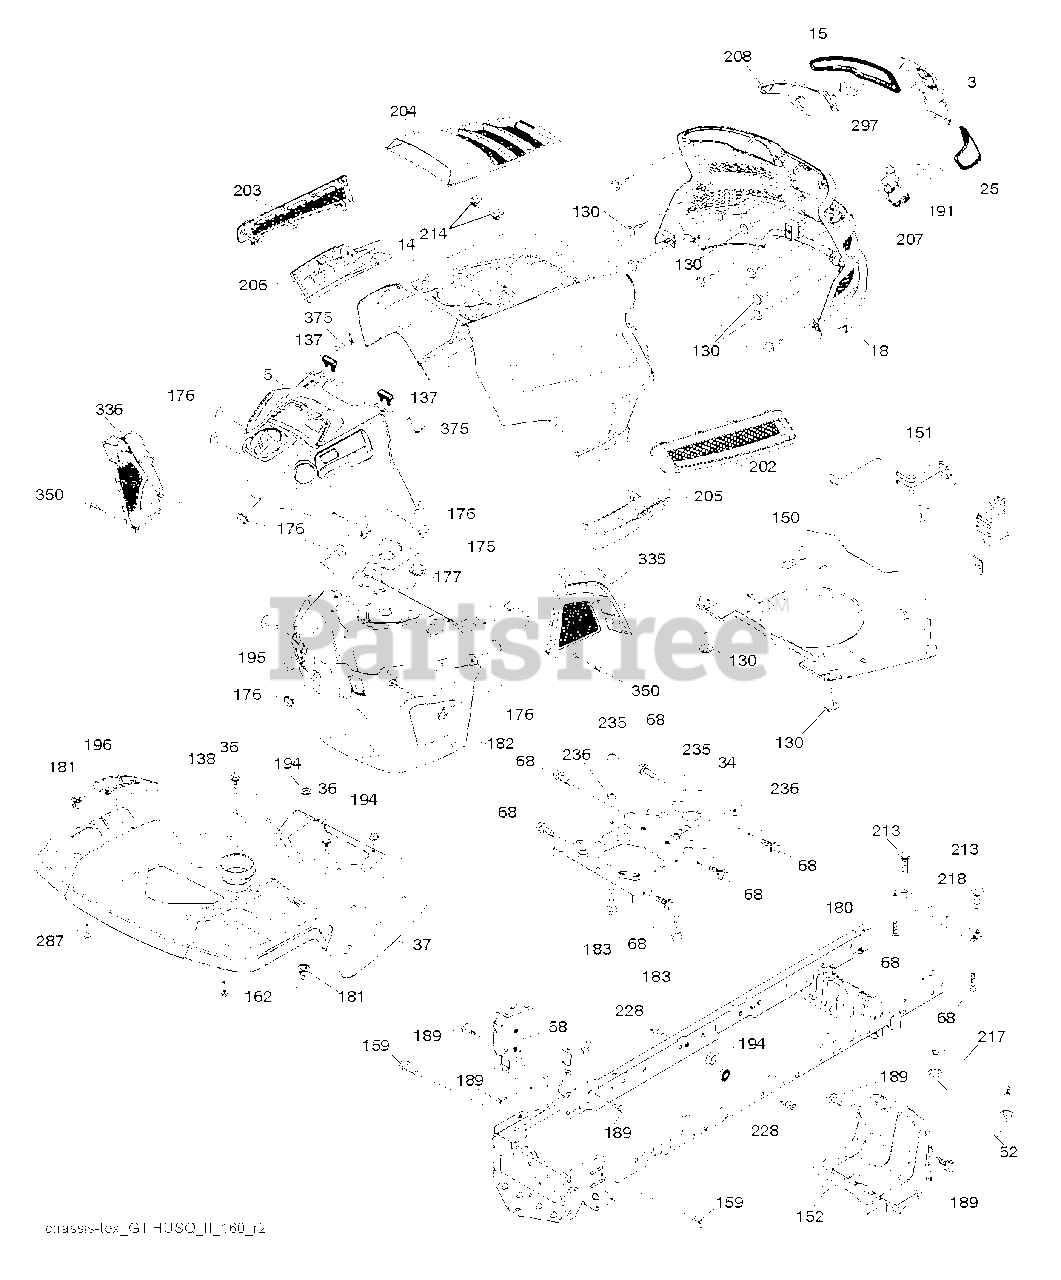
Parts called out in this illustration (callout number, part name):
3	APPLIQUE.SUBASM.GT.HUSQ.II
5	UPPER.GT2.SVC.MINDING.C-O.M;H
14	HOOD.ASM.HUSQVARNA.GT.TEX.ORAN
18	GRILLE SUBASM.GT.II.LOW.HDLGHT
25	LENS.HEADLIGHT.RH.GTII.2011
34	PLATE.ENGINE.WELDED.CHASSIS
36	SCREW 5/16"
37	FENDER.TLT.PDL.CNTRL.W/CPH.ORG
52	LOCKNUT
58	DRAWBAR UPPER 2PC SMALL FENDER
68	SCREW LT
130	SCREW.#10 X 0.750.BOS
137	BUMPER DASH
138	HOLDER.CUP.LT.GREY
150	AIR.DUCT.GTV.BLACK
151	BRACKET.PIVOT.HOOD.GT.HUSQ.II
152	SHIELD.BROWNING.PNT.GT.V2
159	SCREW, 3/8-16X3/4
162	SCREW.HI-LO.CONSOLE
175	PLATE.CROSSMEMBER.HUSQ
176	SCREW.#10-24X5/8.RN.QU
177	BUSHING STEERING
180	CHASS.WLDMNT.TL.12GA/2P.48/54
181	BUSHING.MNT.FEND.CRGO.TEX.49
182	DASH.LOWER.COMMON.12V.ADAPTOR
183	BOLT.5/16-18X1-1/4 FULL THD
189	SCREW
191	INSERT.REFLECTIVE.RH.HUSQ.GTII
194	NUT LOCK HEX FLANGE 5/16-18
195	PLUG.HOLE.DASH.LOWER.12V.BLK
196	DECKLFT.CONSOL FULL ASSM GREY
202	VENT.SIDE.RH.GT.HUSQ.II.
203	VENT.SIDE.LH.GT.HUSQ.II.498
204	VENT.TOP.HUSQ.GT2
205	SIDE.TRIM.RH.GT.HUSQ.II
206	SIDE.TRIM.LH.GT.HUSQ.II.GRAY
207	HEADLIGHT.CUP.BEZEL.HUS.GT2.RH
208	HEADLIGHT.CUP.BEZEL.HUS.GT2.LH
213	BOLT
214	CLIP.RETAINER.TINNER.
217	ROD.PIVOT.HOOD
218	X-PIECE.HOOD.STOP.NON/
228	STUD.FASTNER.W/ANTI-ROTATE
235	SPACER FENDER
236	NUT.CENTERLOCK.5/16-
287	SCREW 1/4X20
297	INSERT.REFLECTIVE.LH.HUSQ.GTII
335	COVER.LOWER.DASH.RH.BLACK
336	COVER-LH.LOWER.DASH.GT2.BLACK
350	CLIP.X-MAS.TREE
375	BUMPER CLIP-ON. DASH 1"
